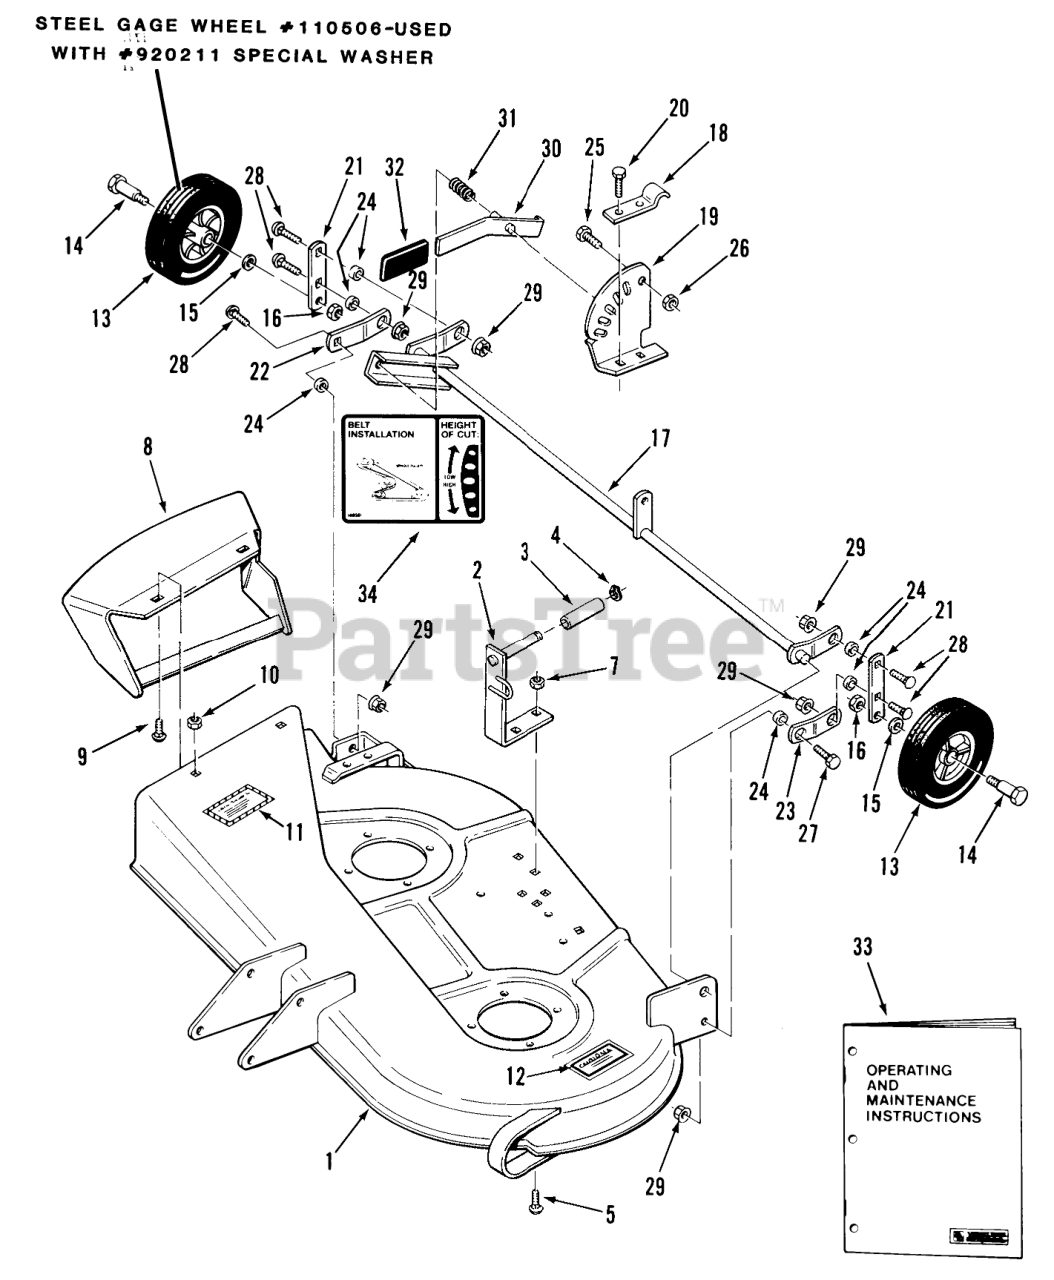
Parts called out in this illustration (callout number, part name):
1	Mower Deck
2	ASSY-BRACKET GUID R
3	SPACER
4	Snap Ring
5	Bolt-Carriage
7	Nut
8	ASSY-CHUTE EXT R
9	CARRIAGE BOLT -4
10	Nut
11	DECAL
12	Caution Decal
13	WHEEL-GAUGE
15	WASHER
16	Nut
17	Gage Wheel Support
18	Pivot Bracket
19	Quadrant
20	Bolt
21	LINK R
22	ARM-PIVOT RH R
23	Arm LH
24	SPACER
26	Nut
27	BOLT
28	Bolt
29	LOCKNUT-FLANGE
30	Lever
31	SPRING-COMPRESSION
33	Operating & Maintenance Instructions
34	DECAL-BELT&HEIGHT
